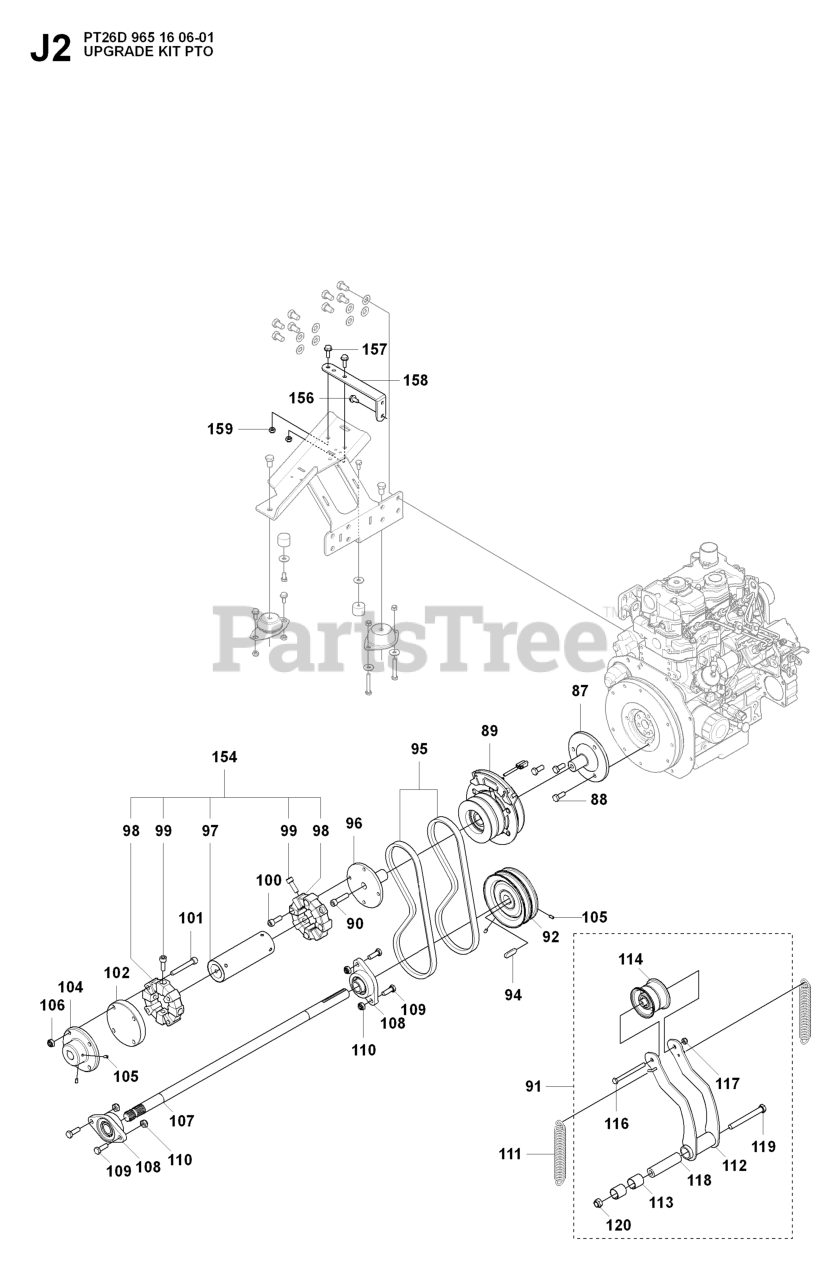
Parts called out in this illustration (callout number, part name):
87	POWER TAKE OFF
95	BELT PTO DOUBLE
97	SHAFT CLUTCH SHORT
98	RUBBER RING CLUTCH
100	SCREW IHSCM M10X30 12.9 ZPB L
101	SCREW IHSCM 10X75 12.9 ZPB
106	NUT
108	BEARING UNIT FYTB 25TF
113	BUSHING
117	NUT
118	SLEEVE 96.5MM
151	Screw M10x25
152	BOLT
157	BOLT
159	LOCKNUT M8
